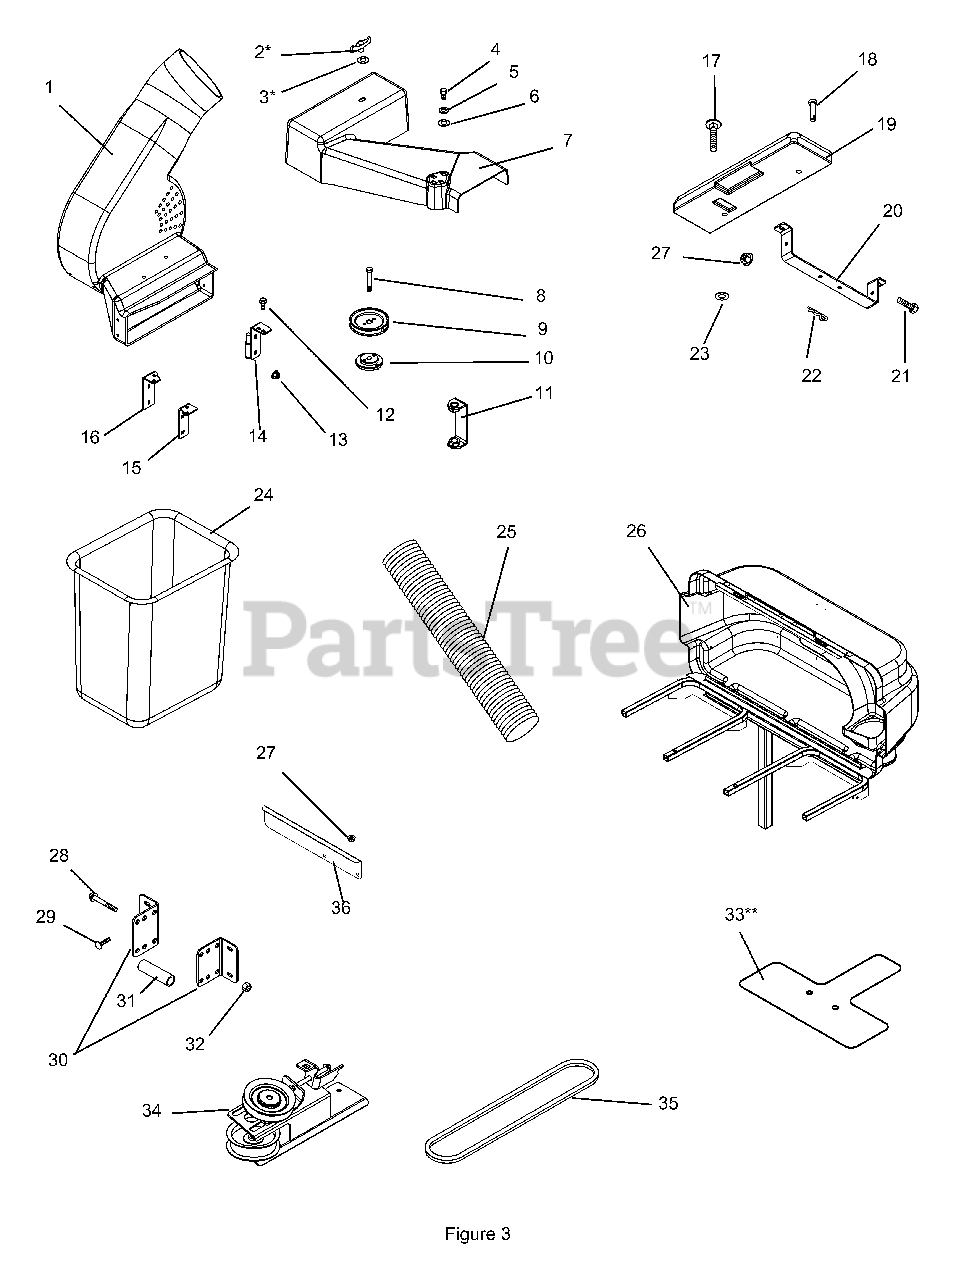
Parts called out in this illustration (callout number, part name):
1	Blower Assembly
2	Wing Knob
3	3/8" x 1-1/2" Washer
4	3/8" x 3/4" Hex Bolt
5	3/8" Lock Washer
6	7/16" x 1" Flat Washer
7	Belt Cover
8	3/8" x 1-3/4" Hex Bolt
9	3-Inch Sheave
9	4-Inch Sheave
10	Sheave Adapter
11	Cover Spacer
12	1/4" x 3/4" Hex Bolt
13	1/4" Top Lock Flange Nut
14	Rear Mount Weldment Bracket
15	Front Bracket
16	Front Mount Weldment Bracket
17	3/8" x 1" Round Head Square Neck Bolt
18	Clevis Pin
19	Counterweight
20	Counterweight Bracket
21	3/8" x 1" Hex Bolt
22	Hair Pin
23	1/2" x 1-5/8" Flat Washer
24	Grass Bagger Basket
26	Cover Assembly
27	3/8" Top Lock Flange Nut
28	1/2" x 3" Hex Bolt
29	3/8" x 1-1/4" Round Head Square Neck Bolt
30	Bagger Mount Bracket
31	Pivot Spacer
32	1/2" Top Lock Flange Nut
33	Finger Guard
34	Idler Assembly
35	40- and 44-Inch V-Belt
35	48- and 52-Inch V-Belt
36	Exhaust Deflector
